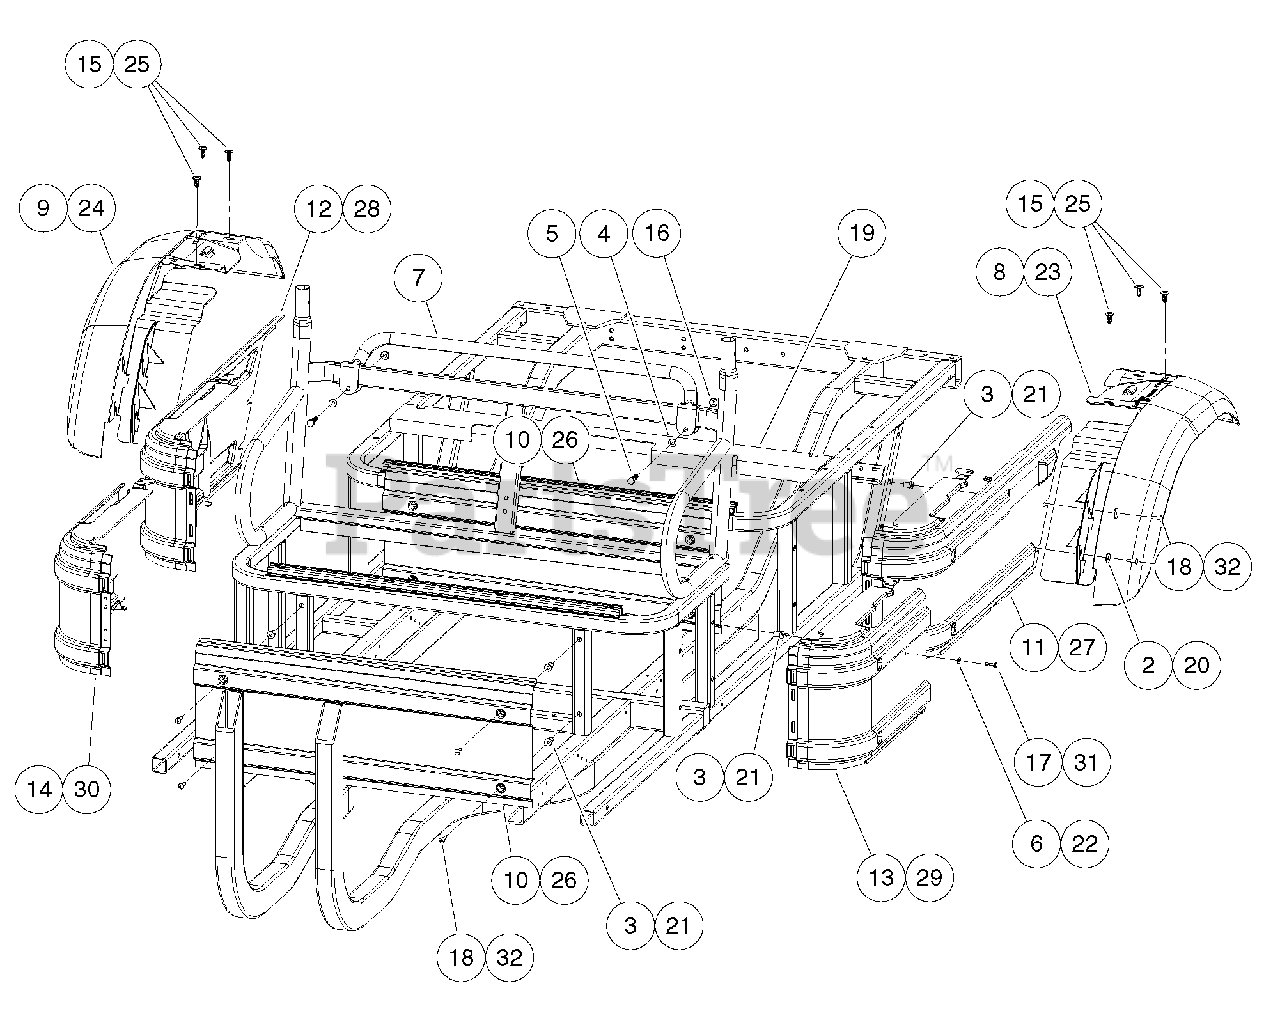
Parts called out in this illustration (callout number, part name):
1	Instl, Pnls, Fend, 4p, Blk
2	Washer, 1/4" Type B Flat
3	Well Nut 1/4-20
4	Washer, Hard, M10, Zn-Ni/Blk
5	Bolt, M10 X 45, Zn-Ni (Black)
6	Washer, Flat, 5/16, Black
7	Weldment, Handle, ROPS, Rear
8	Left Rear Fender
9	Right Rear Fender
10	Panel, Front, Kick
11	Panel, Side, Molded, Driver
12	Panel, Side, Molded, Passenger
13	Panel, Side, Cut, Drv
14	Panel, Side, Molded, Pas
15	Screw, Tuflok, 10mm
16	Nut, Flanged, M10 x 1.5, Black
17	Screw, Pn Hd Blk, 1/4 - 20 X 1
18	Screw, 1/4-20 X 1.0 Truss-Head Machine
19	Instl, Pns, Fndrs, 4p, Rthwd
20	Washer, 1/4" Type B Flat
21	Well Nut 1/4-20
22	Washer, Flat, 5/16, Black
23	Left Rear Fender
24	Right Rear Fender
25	Screw, Tuflok, 10mm
26	Panel, Front, Kick, Rthwhd
27	Pnl, Side, Mld, Drv, Rthwhd
28	Pnl, Side, Mld, Pass, Rthwhd
29	Pnl, Cut, Drv, Rthwhd
30	Pnl, Cut, Pass, Rthwhd
31	Screw, Pn Hd Blk, 1/4 - 20 X 1
32	Screw, 1/4-20 X 1.0 Truss-Head Machine
33	Closeout, Extrusion
